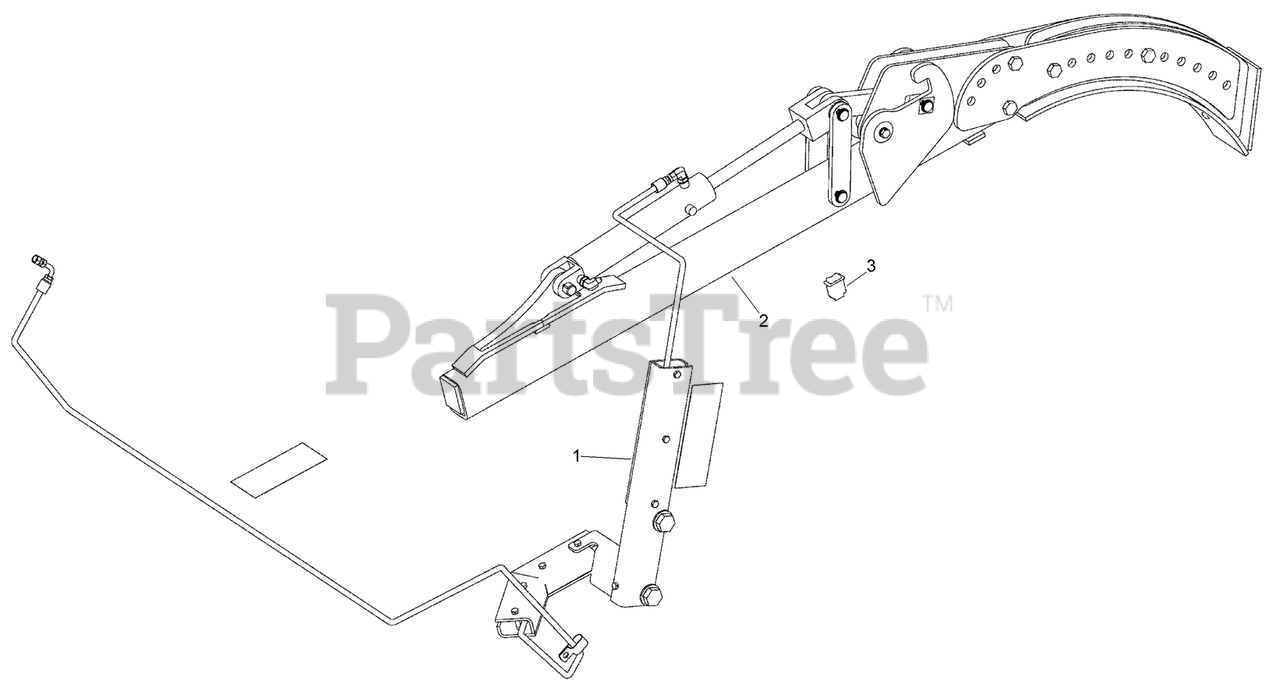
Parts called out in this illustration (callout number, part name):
1	KIT - Hydraulic Crumber
2	WELDMENT - Tube, Crumber
3	SWITCH-ROCKER, 2 POLE
5	BLADE - Hydraulic Crumber, 8 Wide Cut
